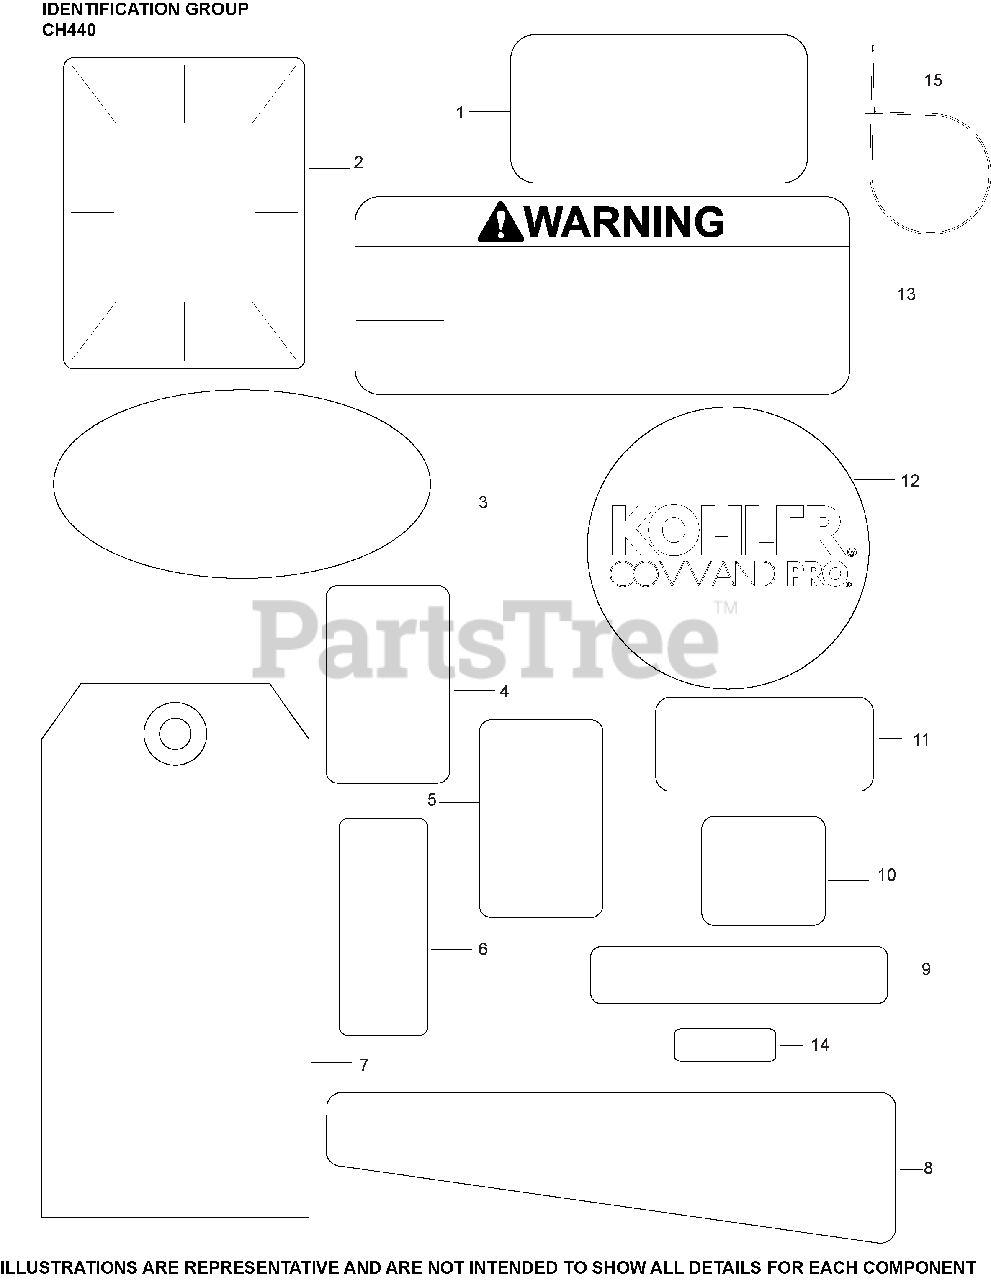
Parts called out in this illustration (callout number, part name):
1	LABEL, MAINTENANCE (CKY)
2	LABEL, CLEAR LAMINATION
3	DECAL, QUAD CLEAN SILVER
4	DECAL, SNOW FLAKE
5	DECAL, SUN
6	DECAL, FUEL/CHOKE - ON/OFF
7	TAG, HANG
8	DECAL, 14 HP/429cc/CH440
10	DECAL, BASE ARROW
11	LABEL, CANADIAN COMPLIANCE
11	DECAL, ETHANOL WARNING
13	DECAL, WARNING
14	DECAL, ENGINE AND FUEL SHUT OFF
17113124-S	LABEL, RECOIL 75MM
